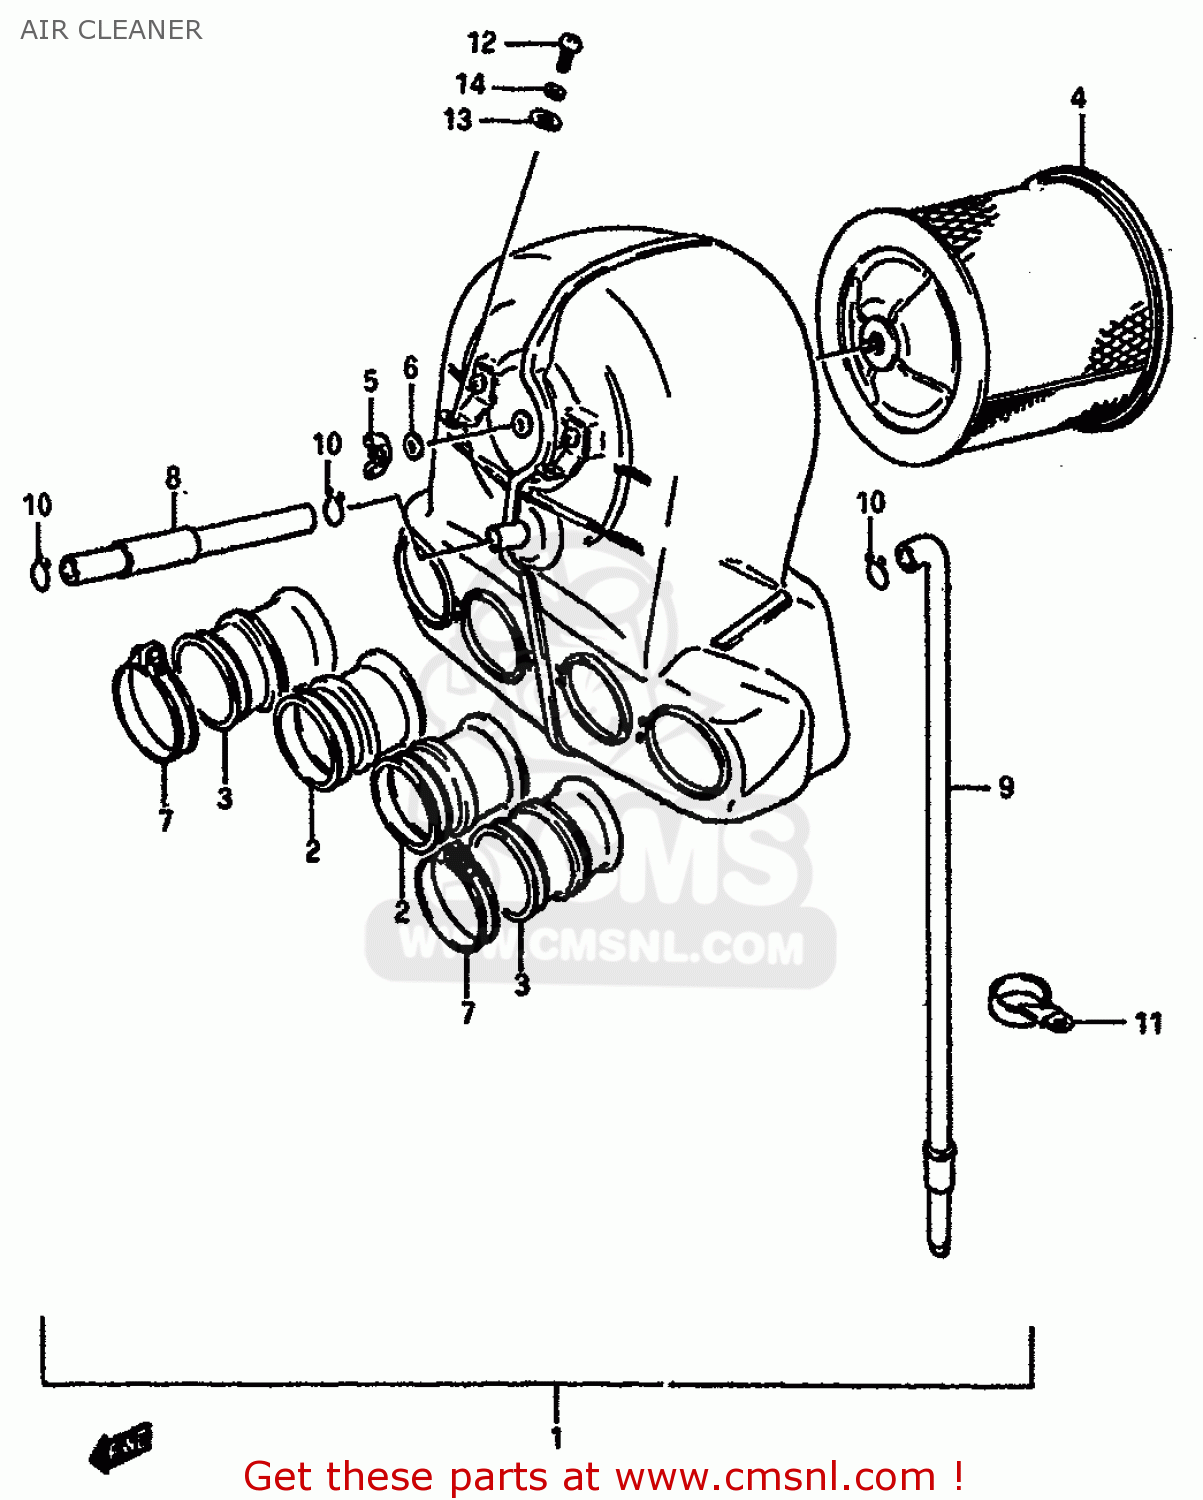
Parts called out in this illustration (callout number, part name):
1	CLEANER ASSY,AIR
2	TUBE,OUTLET NO.1
3	TUBE,OUTLET NO.2
4	FILTER ASSY
5	NUT, WING
6	WASHER 5MM
7	CLAMP
8	TUBE,BREATHER
9	DRAIN TUBE
10	CLIP
11	CLAMP,AIR CLEANER DRAIN TUBE
12	SCREW
13	WASHER(6.5X16X1.2)
14	LOCK WASHER
